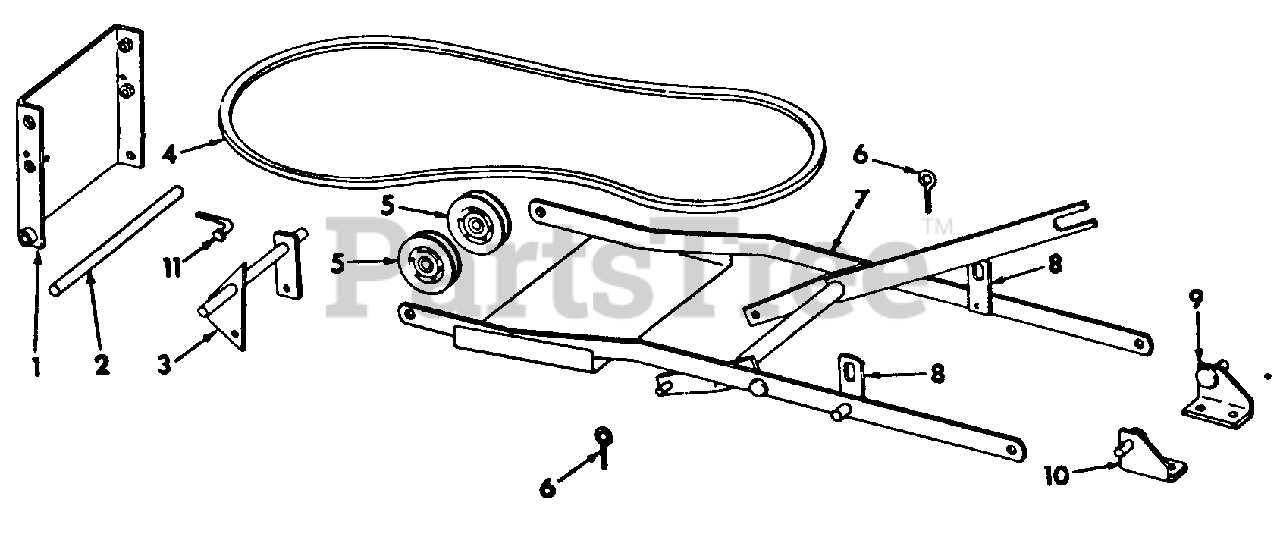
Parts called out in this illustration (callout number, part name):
1	Support Assy, Front
2	Pin, Front Mounting
3	Support Assy, Idler
5	Pulley, Drive Belt Idler -Replaces 473 467 R91
7	Frame Assy, Lift
8	Link Assy, Lift
9	Bracket Assy, Rear Hanger RH
10	Bracket Assy, Rear Hanger LH
